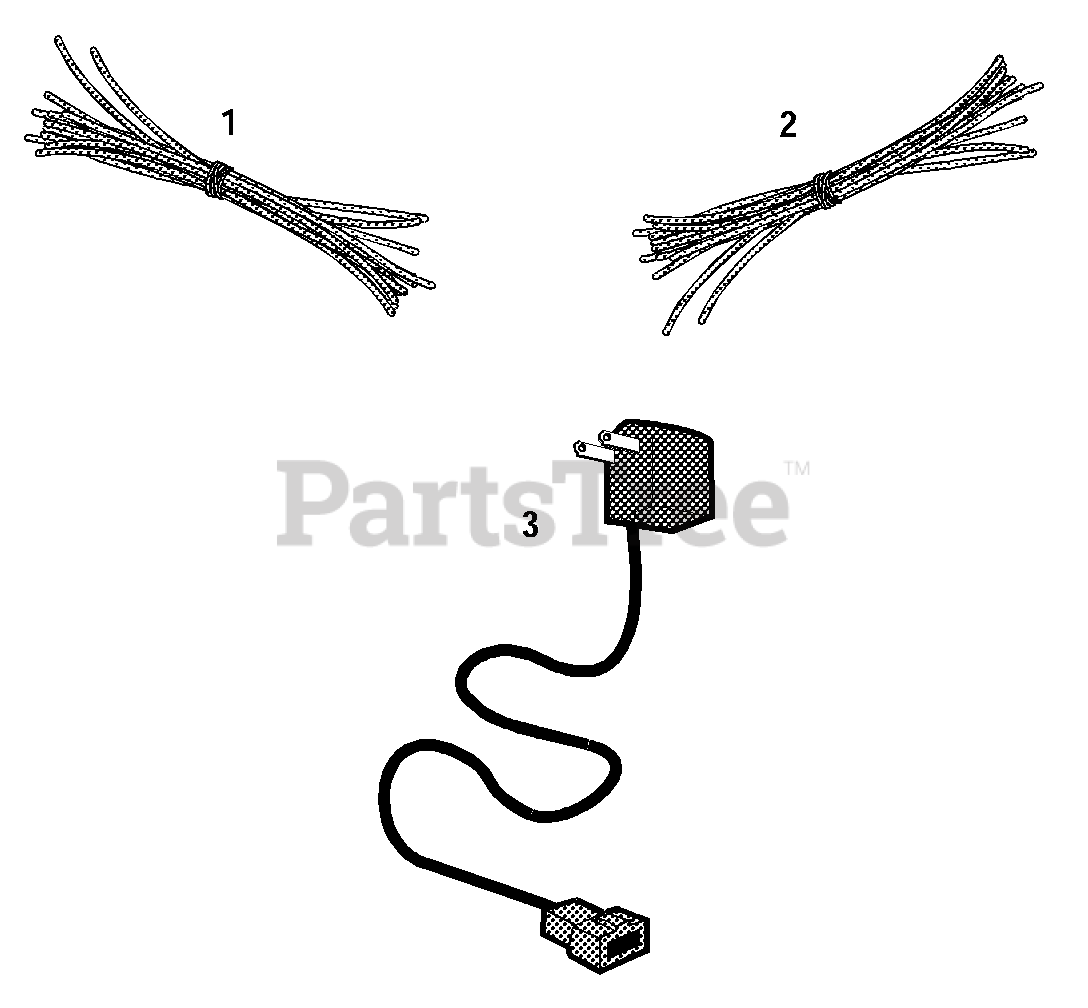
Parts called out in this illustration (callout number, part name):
1	Trimmer String Kit, .155" diameter line (24 pieces)
2	Trimmer String Kit, .130" diameter line (24 pieces)
3	Battery Charger (for electric start model)
